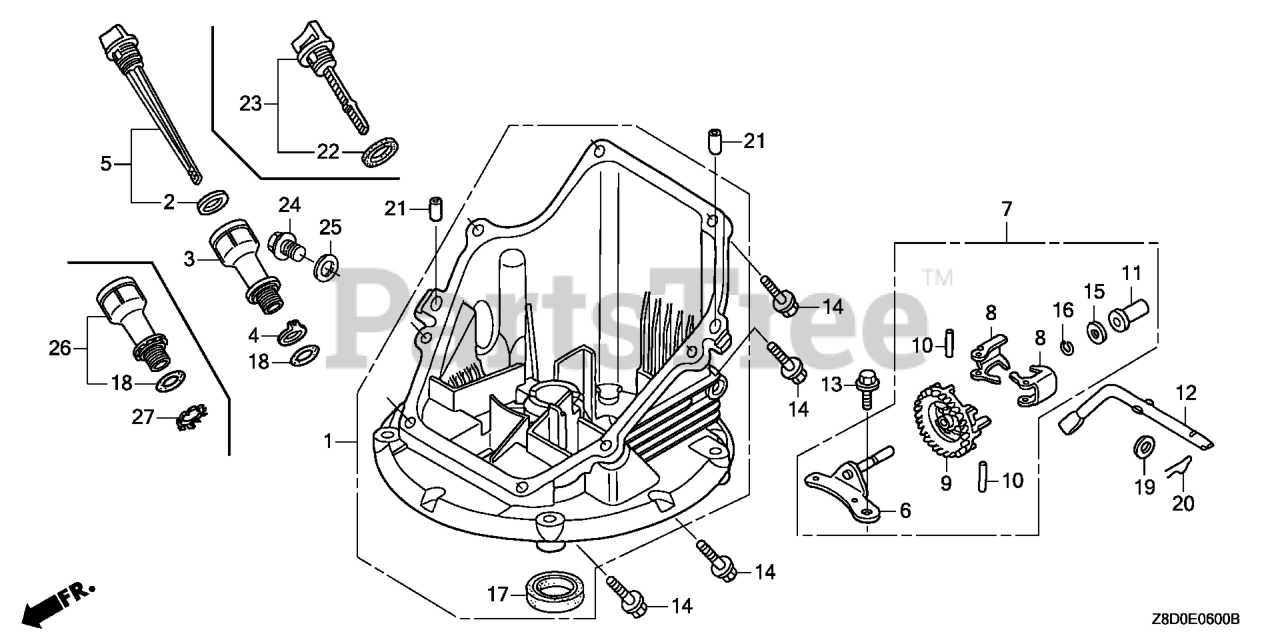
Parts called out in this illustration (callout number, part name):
1	PAN ASSY., OIL
2	GASKET, OIL FILLER CAP Use up to Engine SN 1257294.
5	DIPSTICK, OIL
6	SHAFT, GOVERNOR HOLDER
7	GOVERNOR ASSY.
8	WEIGHT, GOVERNOR
9	HOLDER, GOVERNOR WEIGHT
10	PIN, GOVERNOR WEIGHT
11	SLIDER, GOVERNOR
12	SHAFT, GOVERNOR ARM
13	BOLT, FLANGE (6X14)
14	BOLT, FLANGE (6X25) Use up to Engine SN 2056819.
15	WASHER, THRUST (6MM)
16	CLIP, GOVERNOR HOLDER
17	OIL SEAL (28X41.25X6)
18	O-RING (14.8X2.4) (ARAI)
19	WASHER, PLAIN (6MM)
20	PIN, LOCK (8MM)
21	PIN, DOWEL (8X20)
26	EXTENSION, OIL FILLER
27	WASHER, EXTENSION LOCK
